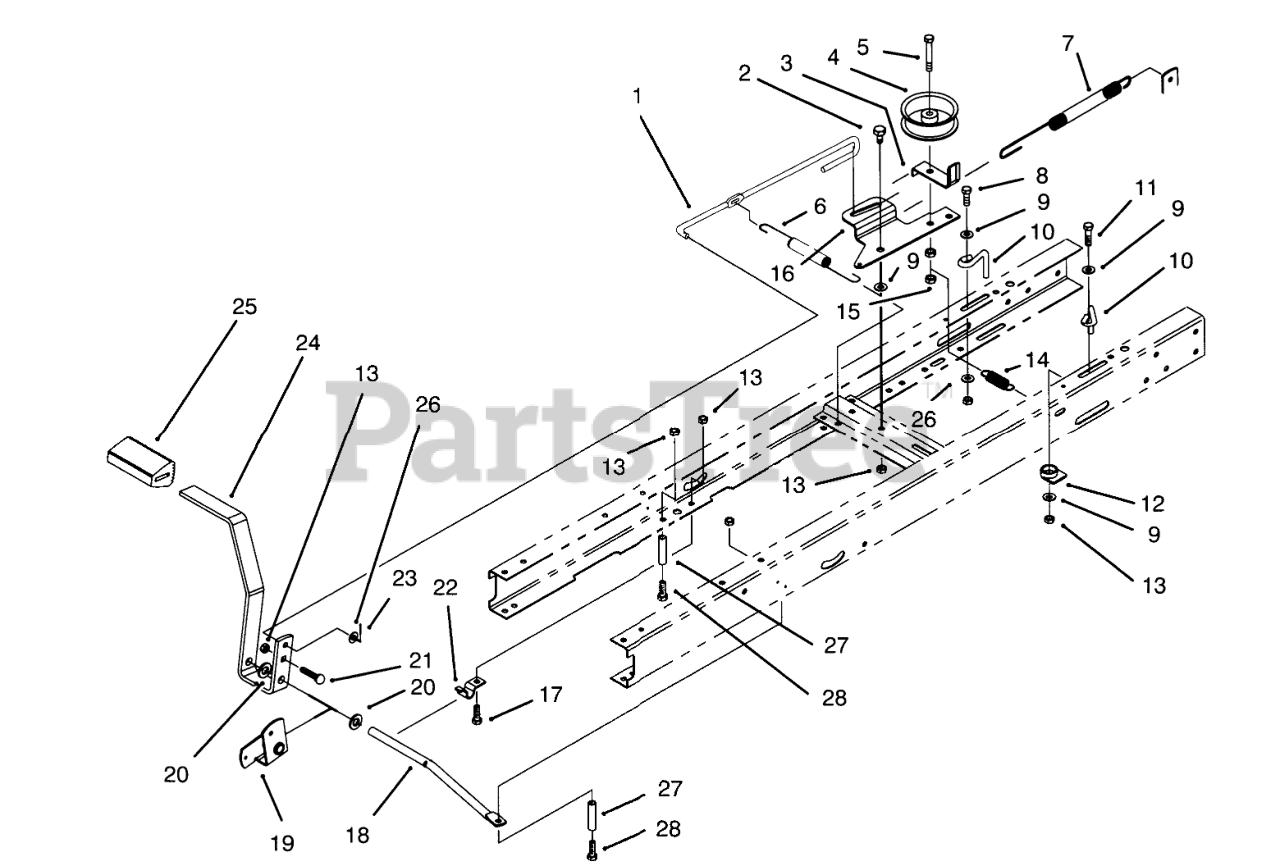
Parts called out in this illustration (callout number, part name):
1	ROD-CLUTCH/BRAKE
2	BOLT-SHOULDER
3	GUIDE-IDLER, BELT
4	Idler Pulley
5	SCREW-HH
6	SPRING-EXTENSION
7	BRAKE SPRING
8	SCREW-HH
9	WASHER-PIVOT
10	TRANS BELT GUIDE
11	SCREW-HH
12	GUIDE-CABLE
13	NUT-LOCK, NI
14	SPRING-EXTENSION
15	NUT-LOCK, NI
16	ARM-IDLER
17	SCREW-HH
18	ROD-PIVOT, PEDAL
19	BelIcrank
20	WASHER-FLAT
21	SCREW-CARR
22	CLAMP-PIVOT, SHIFT
23	PIN-COTTER
24	Pedal-Clutch/Brake
25	PAD-PEDAL
26	WASHER-PLAIN
27	TUBING-SPACER
28	SCREW-HH
